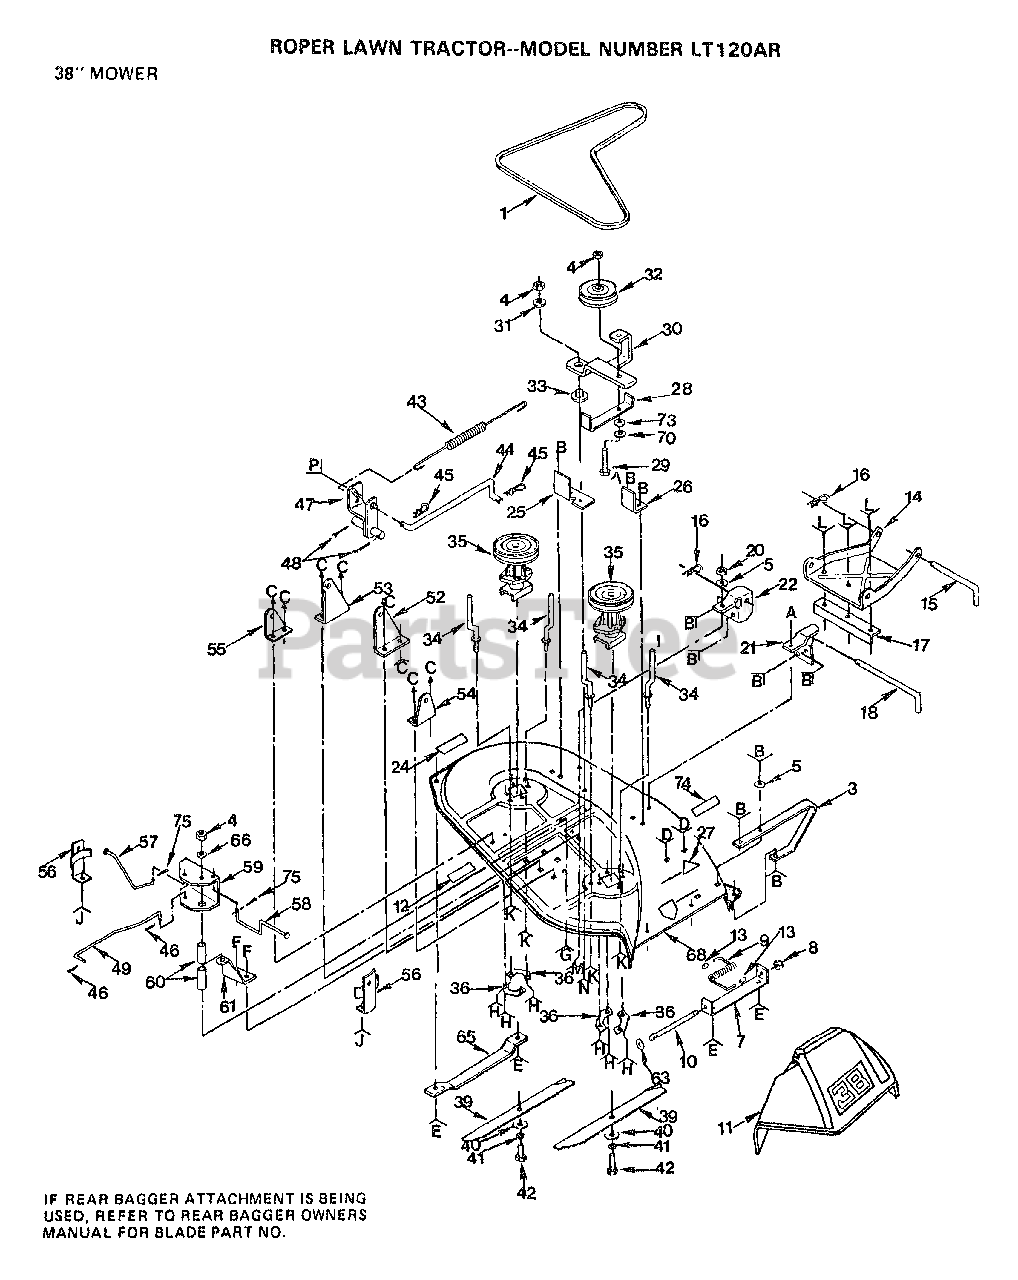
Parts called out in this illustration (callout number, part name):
1	BELT-V.79.1.MWR
5	WASHER M
10	ROD-HINGE T
11	DEFLECTOR-SHLD T
12	DECAL.LT
14	LINK.PARALLEL
15	"ROD, FRT. PARAL T"
16	RETAINER.SPRING
17	LINK STOP
21	BRACKET RH LT
22	BRACKET LH T
24	DECAL INSTRUCTION CAUTION
27	DECAL - SAFETY STANDARD
31	SPACER RETAINER
32	IDLER-FLAT T
33	"WASHER, WEAR LT"
34	BELT KEEPER LT
36	SUPPORT PLATE LT
40	WASHER
42	BOLT.3/8-24X1-1/2
47	ROCK SHAFT LT
49	ROD BRAKE LT
54	"BRKT,SUSP RH T"
55	"BRKT,SUSP REAR LH"
56	BRAKE LT
57	"ROD, BRAKE LH LT"
58	ROD BRAKE LT
59	"BRK,BRAKE,PVT LT"
60	SPACER BRAKE LTV
61	BRACKET SUPT LTV
63	WASHER
65	RUNNER-LH M
66	WASHER
70	WASHER
73	WASHER
74	DECAL.WARNING.T
